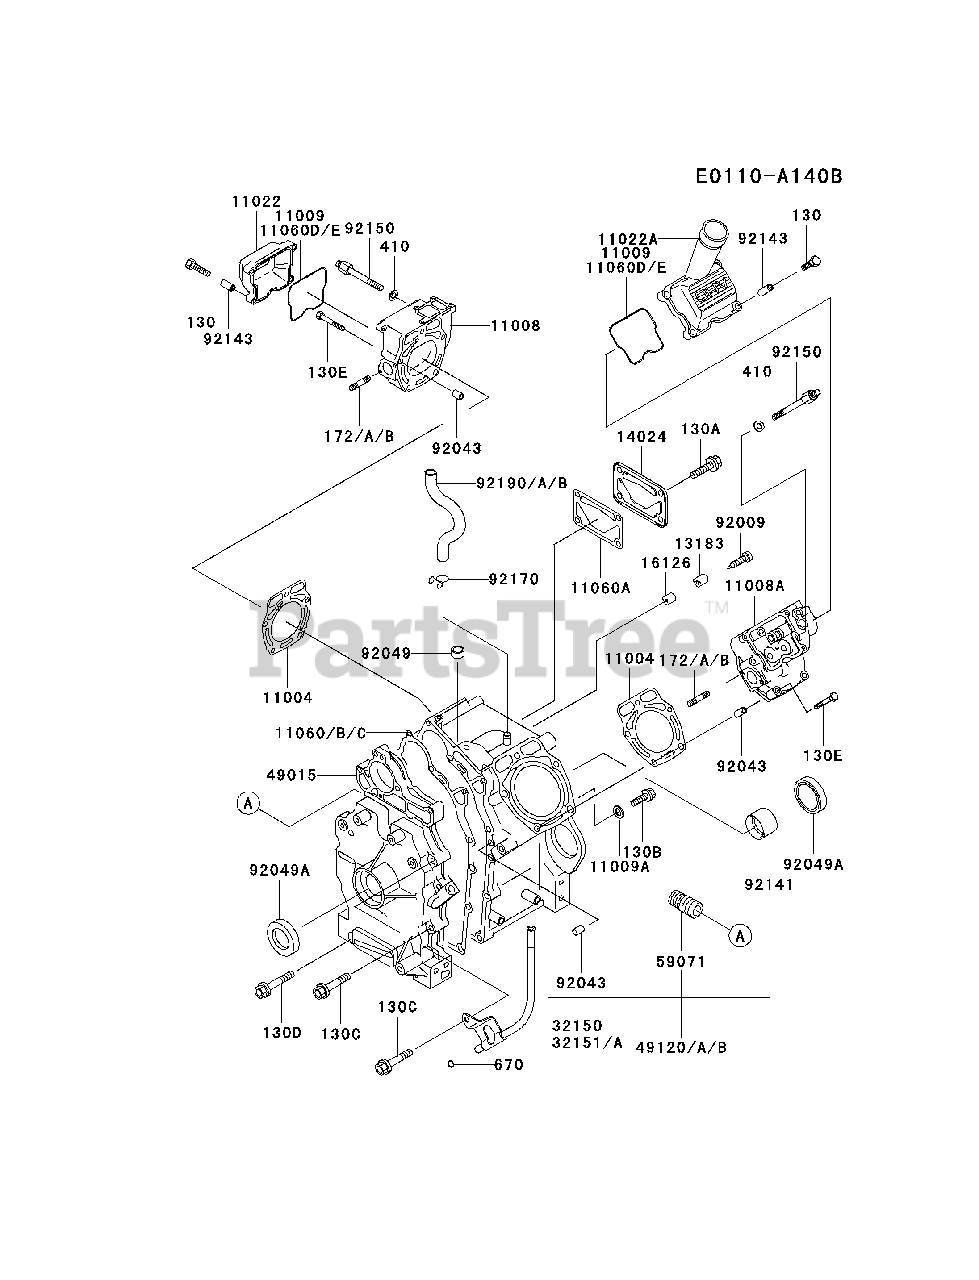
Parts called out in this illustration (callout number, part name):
130	BOLT-FLANGED
130A	BOLT-FLANGED
130B	BOLT-FLANGED
130C	BOLT-FLANGED
130D	BOLT-FLANGED
130E	BOLT-FLANGED
172A	BOLT-STUD
410	W-PLAIN-S
